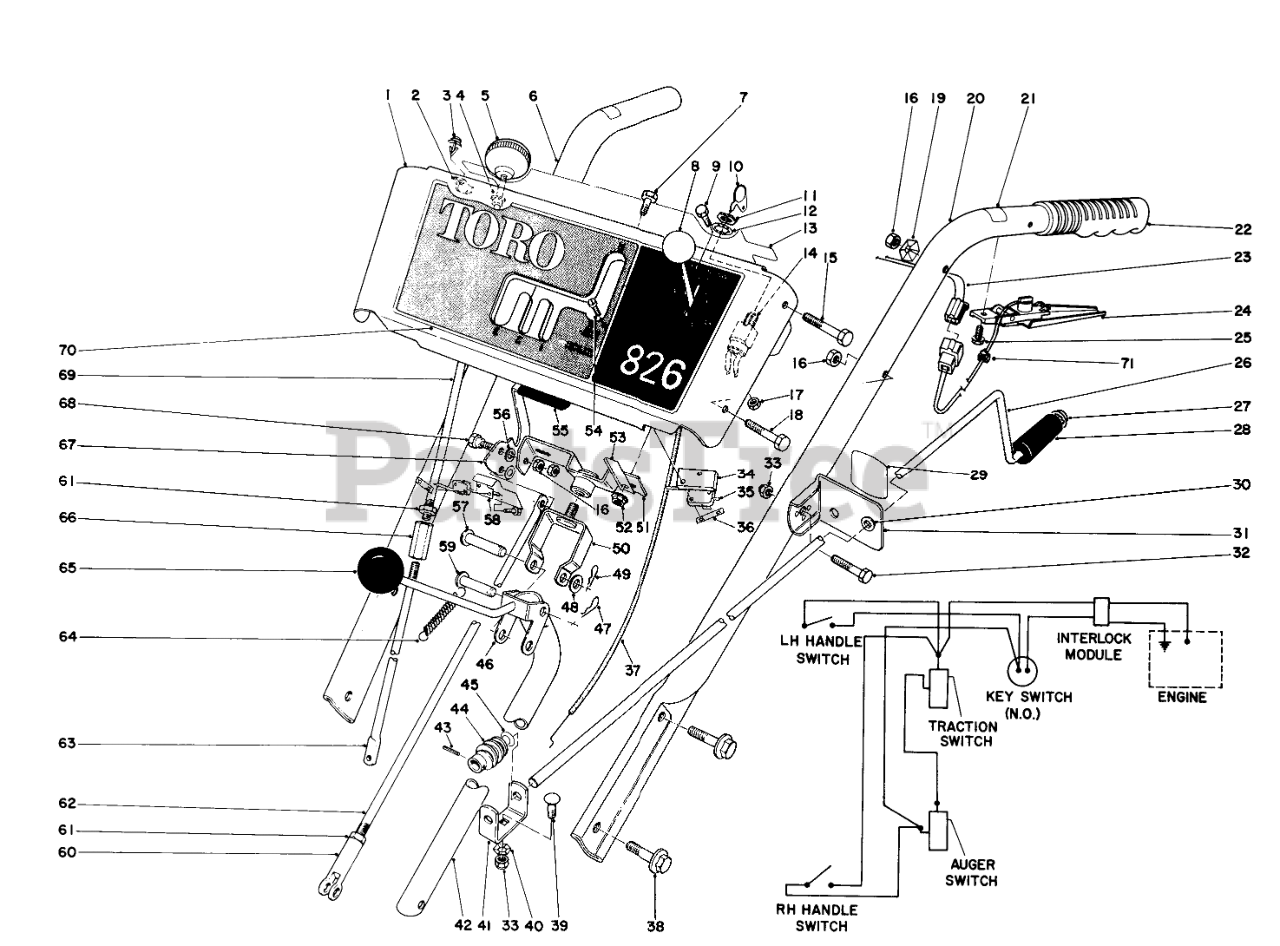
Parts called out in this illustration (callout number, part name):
1	Escutcheon Plate (Incl. Ref. #13 & 70)
2	WIRE CLAMP
3	Mounting Stud
4	NYLINER #6LI-FF TYPE 7
5	KNOB-LEVER
6	Handle Right
7	SCREW-HH
8	CONTROL KNOB
9	HEX HEAD SEMS 10-24X1/2
10	Key
11	NUT-HH
12	WASHER-TOOTH, INTERNAL
13	BACK ESCUTCH DECAL
14	Key Switch (Incl. Ref. #11 & 12)
15	SCREW-HH
16	NUT-LOCK, CONE
17	NUT-LOCK, NI
18	SCREW-HH
19	Washer
20	HANDLE LEFT
21	INTERLOCK DECAL
22	Grip Handle
23	WIRE HARNESS INTERLOC
24	Interlock Handle & Switch (Incl. Ref. #71)
25	SCREW
26	Chute Control Rod
27	RETAINER-PUSH ON
28	GRIP-CONTROL, CHUTE
29	CHUTE DECAL
30	Bushing
31	Bracket-Chute Control Mtg. (Incl. Ref. #29 & 30)
32	SCREW-HH
33	NUT-LOCK, NI
34	SWITCH MTG PAD
35	SWITCH-MICRO
36	NUT-SPEED
37	Throttle Contrl
38	SCREW-HHF
39	BOLT-CARR
40	WASHER-LOCK
41	WORM BRACKET
42	Rod Traction Shift
43	PIN-SPRING
44	GEAR-WORM, CHUTE
45	WASHER-SPRING
46	SHIFT ROD WA
47	PIN-COTTER
48	WASHER-FLAT
49	PIN-HAIR
50	PIVOT BRKT WA
51	SWIVEL BLOCK WA
52	NUT-LOCK, HHF
53	Retainer Wire
54	SCREW-SPH
55	AUGER CLUTCH HND GRIP
56	WASHER-PLAIN
57	PIN-CLEVIS
58	SWITCH BRKT
59	PIN-CLEVIS
60	CLEVIS
61	NUT-HJ
62	DRAG LINK
63	LOWER WHL CLUTCH ROD
64	CONT ROD SPRING 0
66	WHL ROD COUPLING
67	Auger Clutch Handle
68	SCREW-SHOULDER
69	UP WHEEL CLUTCH ROD
70	ESCUTCHEON DECAL
71	Mount-Wire
